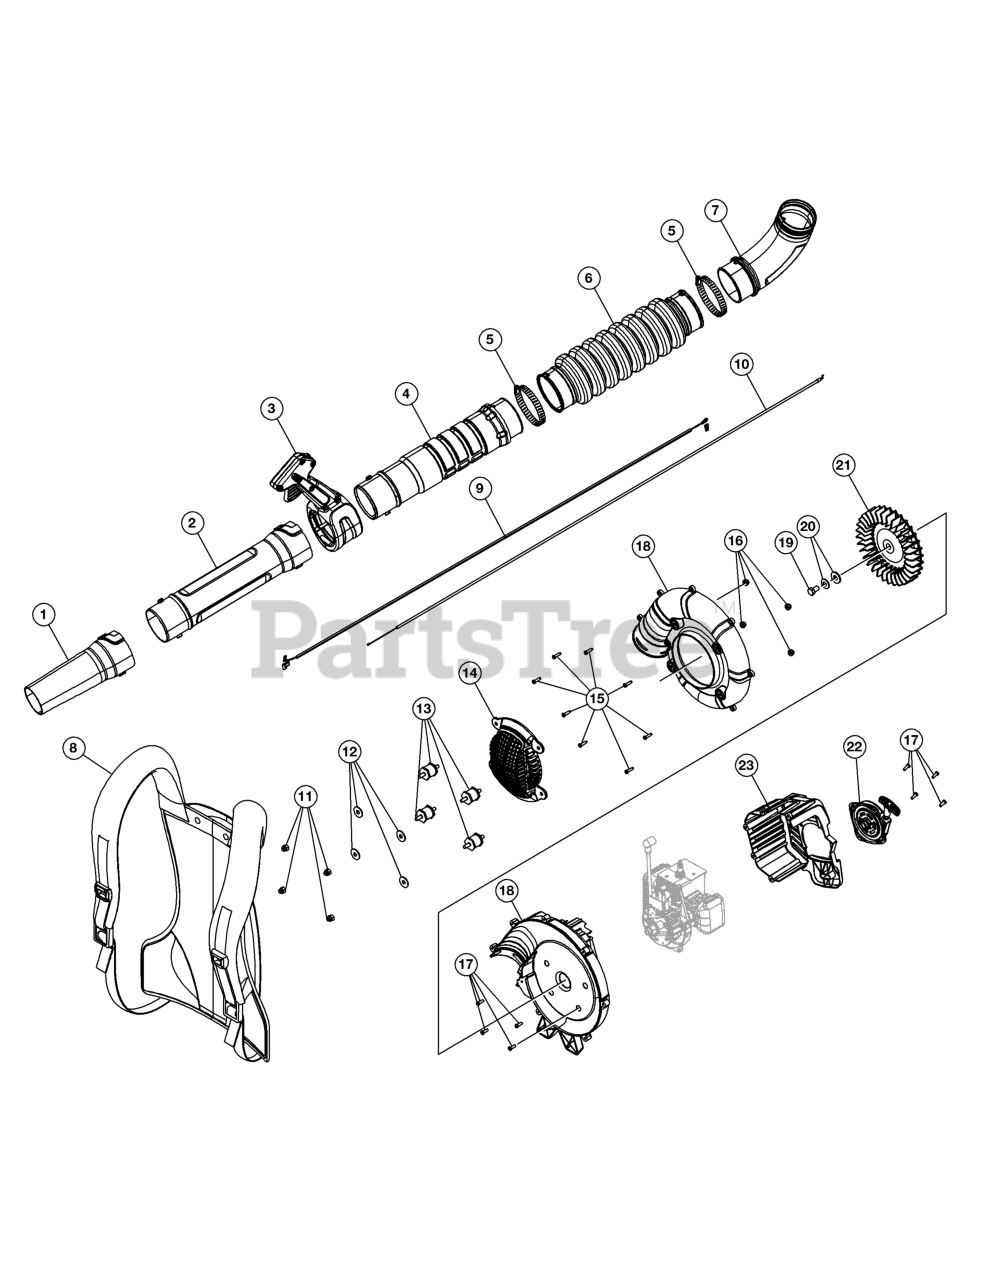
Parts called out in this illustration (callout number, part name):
2	Lower Blower Tube
3	Throttle Grip Assembly
4	Upper Blower Tube
10	Throttle Cable
11	Nut
12	Washer
13	Insulator Mount
14	Intake Cover
17	Screw
18	Impeller Housing Assembly (Incl. 13 - 17)
20	Impeller Hardware (Incl. 19)
21	Impeller (Incl. 19 & 20)
22	Starter Assembly (Incl. 17)
